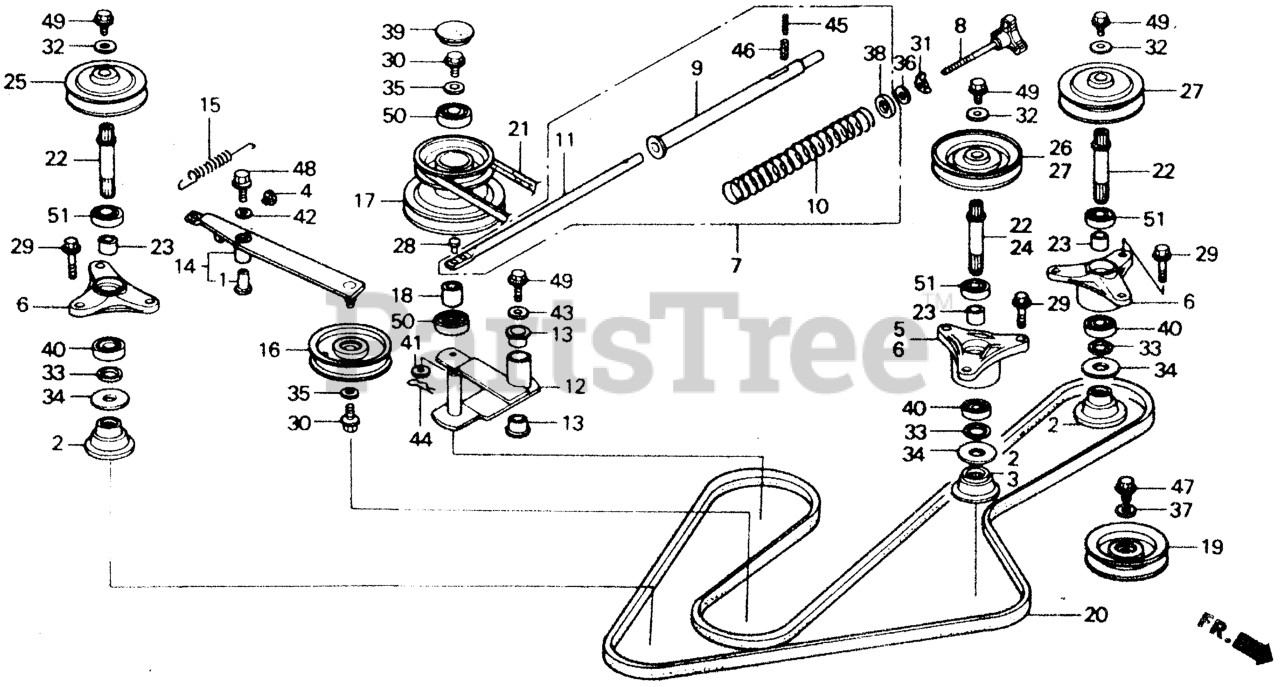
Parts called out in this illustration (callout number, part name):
1	BUSH (15X19X39.5)
2	HOLDER, BLADE
3	HOLDER, BLADE
4	RUBBER, STOPPER
5	HOUSING, BEARING
6	HOUSING, BEARING
7	PIPE ASSY., TENSIONER
8	KNOB, TENSIONER SPRING RELEASE
9	PIPE, SPRING SETTING
10	SPRING, TENSIONER LOAD SETTING
11	SHAFT, SPRING SET
12	ARM, TENSION
13	BUSH, TENSIONER ARM
14	ARM, TENSIONER (DECK)
15	SPRING, TENSIONER ARM B
16	ROLLER, TENSIONER
17	PULLEY, DRIVEN
18	COLLAR, DRIVEN PULLEY
19	PULLEY, TENSIONER
20	V-BELT, BLADE (LB-98)
21	V-BELT, DECK (LB-104)
22	SHAFT, BLADE
23	COLLAR, BLADE SHAFT
24	SHAFT, BLADE (112.5MM)
25	PULLEY, R. DECK
26	PULLEY, BLADE (120MM)
27	PULLEY, DECK
28	PIN, TENSIONER ARM (10X19.5)
29	BOLT, FLANGE (10X28)
30	BOLT, WHEEL
31	WINGNUT (8MM)
32	WASHER (10.5X27X4)
33	WASHER, THRUST (20MM)
34	WASHER, BLADE HOLDER
35	WASHER (8MM)
36	WASHER, TENSIONER SPRING RELEASE (8.3X23X3.2)
37	WASHER (6MM)
38	WASHER, BRAKE SPRING SETTING
39	PLUG, SEALING (40X8)
40	BEARING, RADIAL BALL
41	WASHER, PLAIN (10MM)
42	WASHER, PLAIN (8MM)
43	WASHER, PLAIN (10MM)
44	PIN, LOCK (10MM) Use from Frame SN 2149606 to 2149605.
45	PIN, SPRING (3X28)
46	PIN, SPRING (5X28)
47	BOLT, FLANGE (6X12) Use from Engine SN 2086984.
48	BOLT, FLANGE (8X12)
49	BOLT, FLANGE (10X16)
50	BEARING, RADIAL BALL (6203UU)
51	BEARING, RADIAL BALL (6204UU)
